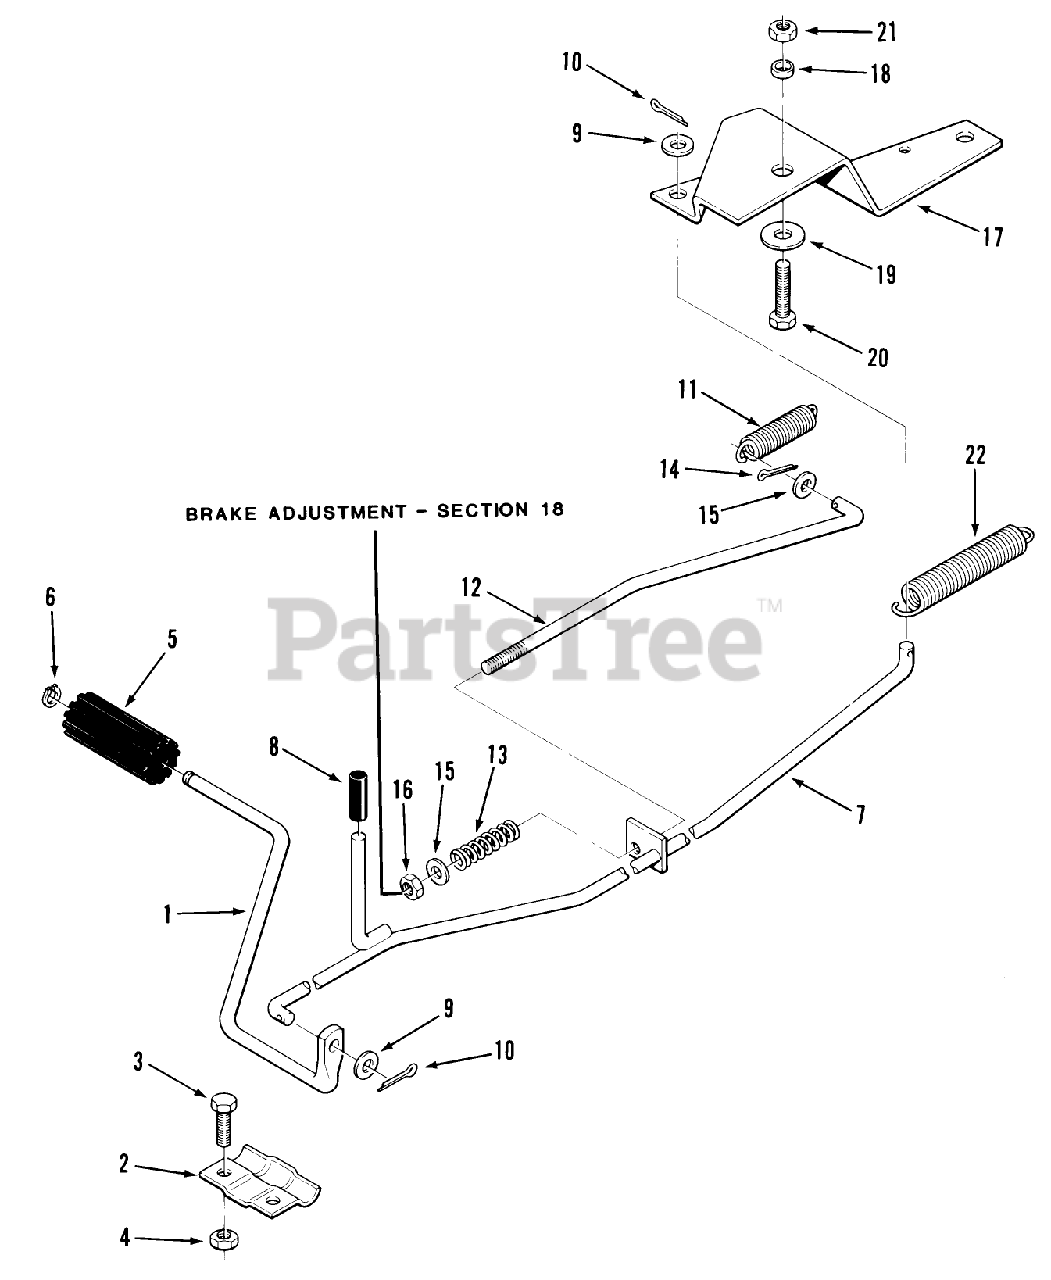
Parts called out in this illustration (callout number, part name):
2	SPINDAL SUPPORT *R
11	SPRING-EXTENSION
13	SPRING-CLUTCH
19	WASHER
